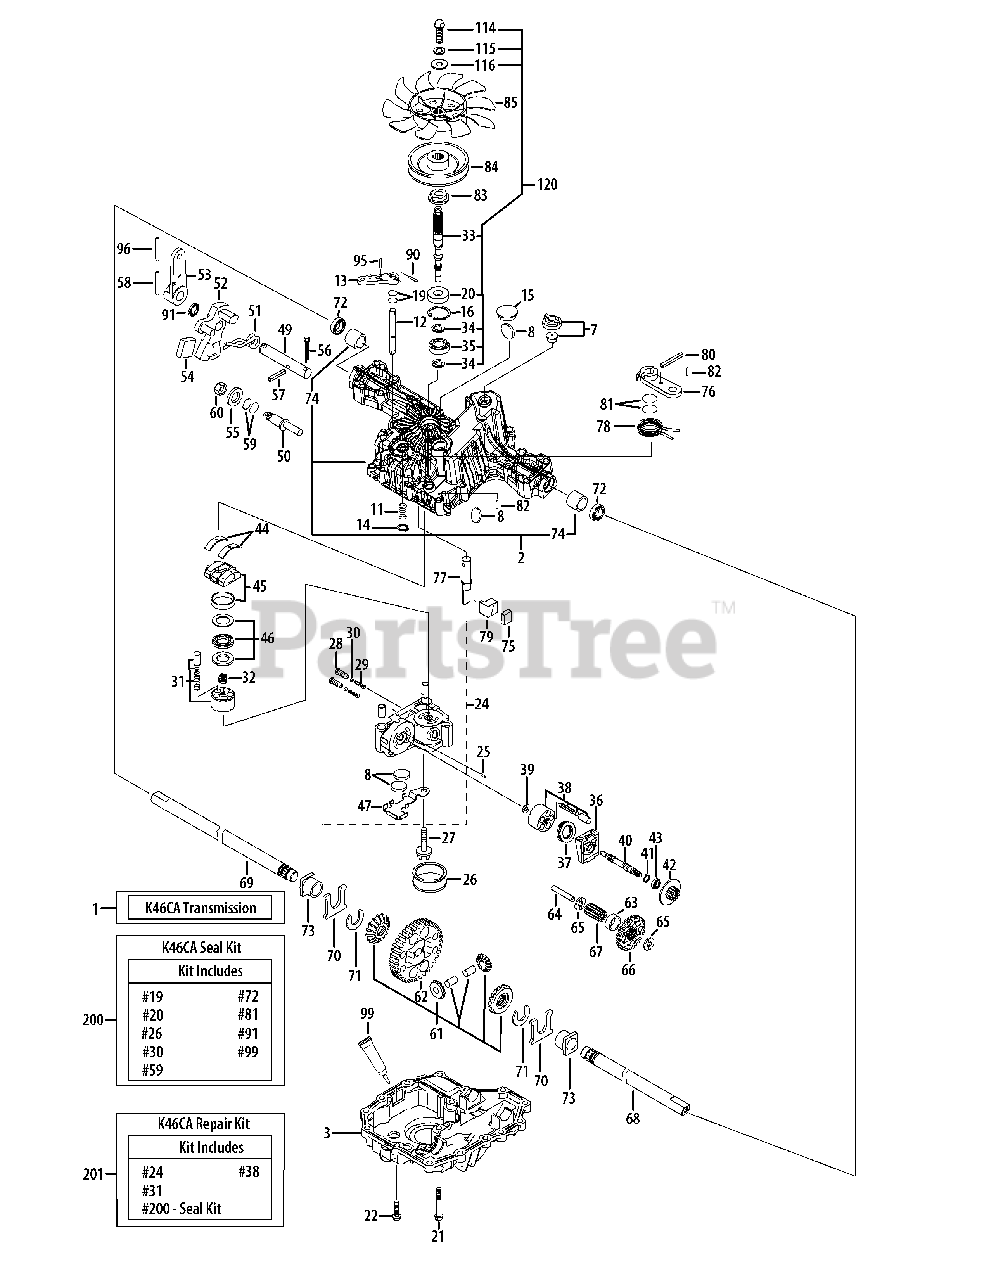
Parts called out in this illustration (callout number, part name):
1	Transmission Asm-Hydro
2	Kit, Upper Case
3	Lower Case
7	Vent Valve 15
12	Bypass Shaft A
14	Snap Ring 10
15	Sealing Cap 30
16	Snap Ring C 35
19	O-Ring 1A P10A
20	Seal TC 153507
21	Tapping Screw 8 x 55
22	Tapping Screw 8 x 30
24	Kit, Center Case C
26	Filter 105
28	IDS Valve 1.2
30	IDS Filter 300
31	Kit, Cylinder Block (Pump)
34	E-Ring 15
35	Bearing 6202C3
36	Motor Housing
37	Thrust Bearing 51106
38	Kit, Cylinder Block
39	Washer 12 x 24 x 1
41	Snap Ring C15
42	Brake Disc/Motor Gear (11T)
43	Bearing 6202 RSR C3
44	Thrust, Plastic
45	Swash Plate Assembly
46	Kit, Thrust Bearing (Pump)
47	Magnet Holder
49	Control Shaft
51	Torsion Spring, Standard
52	Control Arm A
53	Control Lever F
56	Cotter Pin 1/8" x 3/4"
57	Spring Pin 6 x 36
58	Roll Pin 6 x 40
61	Diff Gear Kit
62	Final Gear (54T)
63	Final Pinion Collar
64	Reduction Shaft
65	Washer 12 x 32 x 3.2
66	Reduction Gear (37T)
67	Final Pinion Gear (10T)
68	Axle Shaft, Left
69	Axle Shaft, Right
70	Thrust Washer
72	Seal 19 x 32 x 8
73	Bushing 19 x 25
74	Bushing 19.05
78	Brake Return Spring
79	Brake Actuator
80	Spring Pin 5 x 32
81	O-Ring 1A P12
82	Spring Pin 4 x 16
83	Spline Collar
90	Spring Pin 3.0A x 20
91	Oil Seal 16 x 22 x 03
95	Spring Pin 3.0A x 16
96	Roll Pin 3.5 x 40
99	Sealant
120	Pump Shaft/Bearing Kit
200	Kit,Seal
201	Repair Kit,
